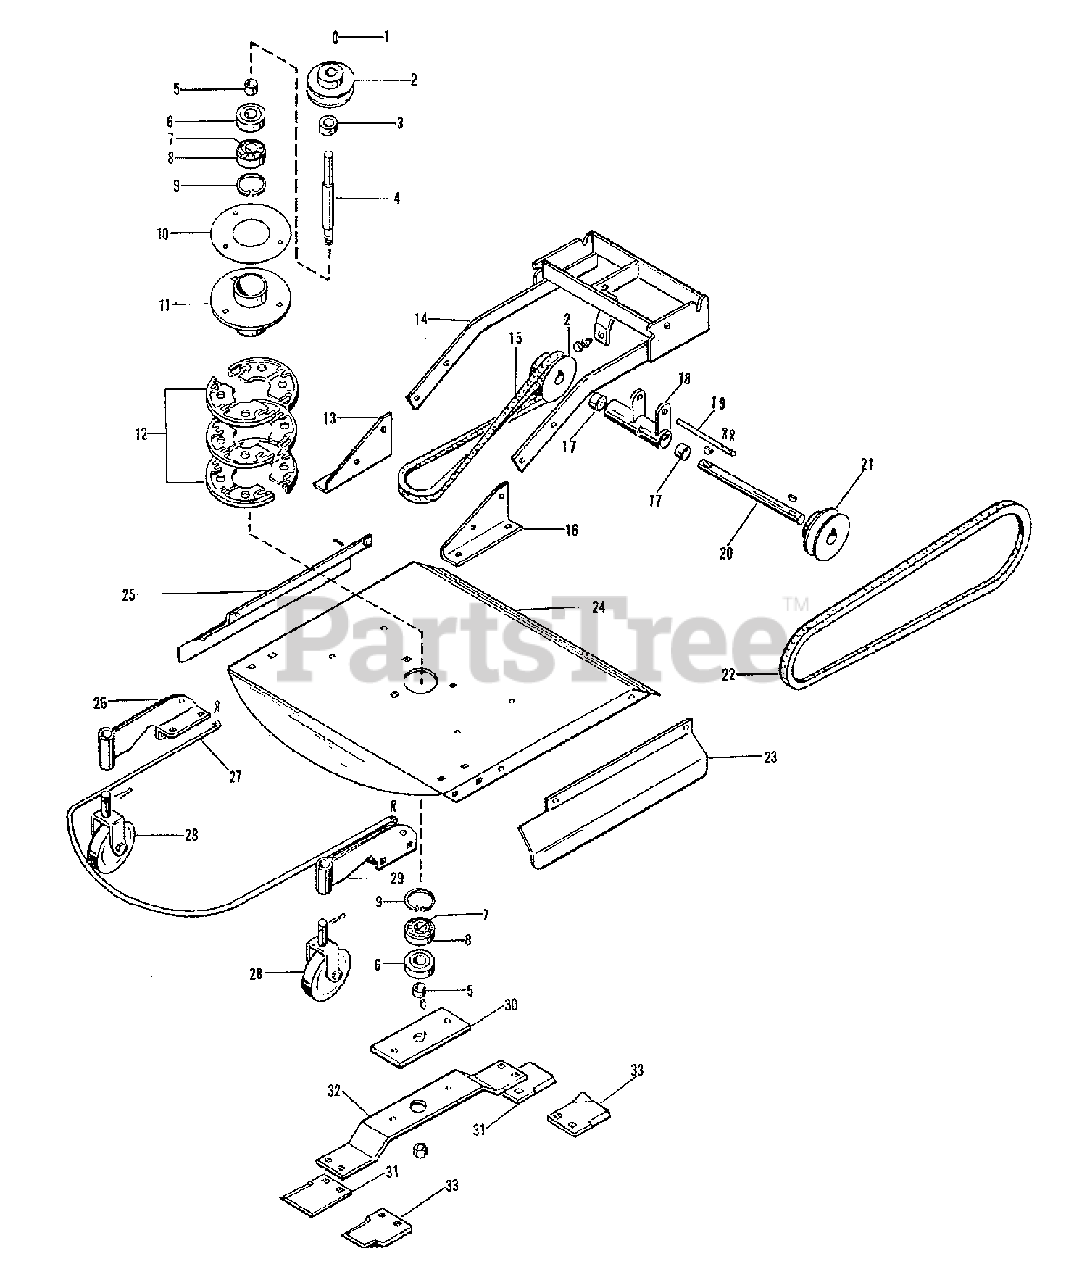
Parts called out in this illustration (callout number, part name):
1	KEY, Arbor Pulley
2	PULLEY, Arbor
3	COLLAR, Set
5	SPACER, Arbor
6	SEAL, Oil
7	ROLLER BEARING, Cone
8	ROLLER BEARING, Cup
9	RING, Retaining
10	WASHER, Spacer Clamp
11	BEARING HOUSING, Arbor
12	SPACER, Height Gage
13	BRACKET, R.H. Push Arm
14	ARM ASSEMBLY, Push
15	BELT, "V" 27"
16	BRACKET, L.H. Push Arm
17	BEARING, Needle
18	TIGHTENER ASSEMBLY, Belt
19	PIN, Pivot
20	SHAFT, Belt Tightener
21	PULLEY, Drive
22	BELT, "V" 36"
23	GUARD, L.H. Cutter
25	GUARD, R.H. Cutter
26	BRACKET, R.H. Caster Wheel
27	GUARD, Front
28	WHEEL ASSEMBLY, Caster
29	BRACKET, L.H. Caster Wheel
30	FLANGE, Arbor
31	BLADE, Cutter
32	BAR, Cutter Blade
33	BLADE, Lift Cutter
